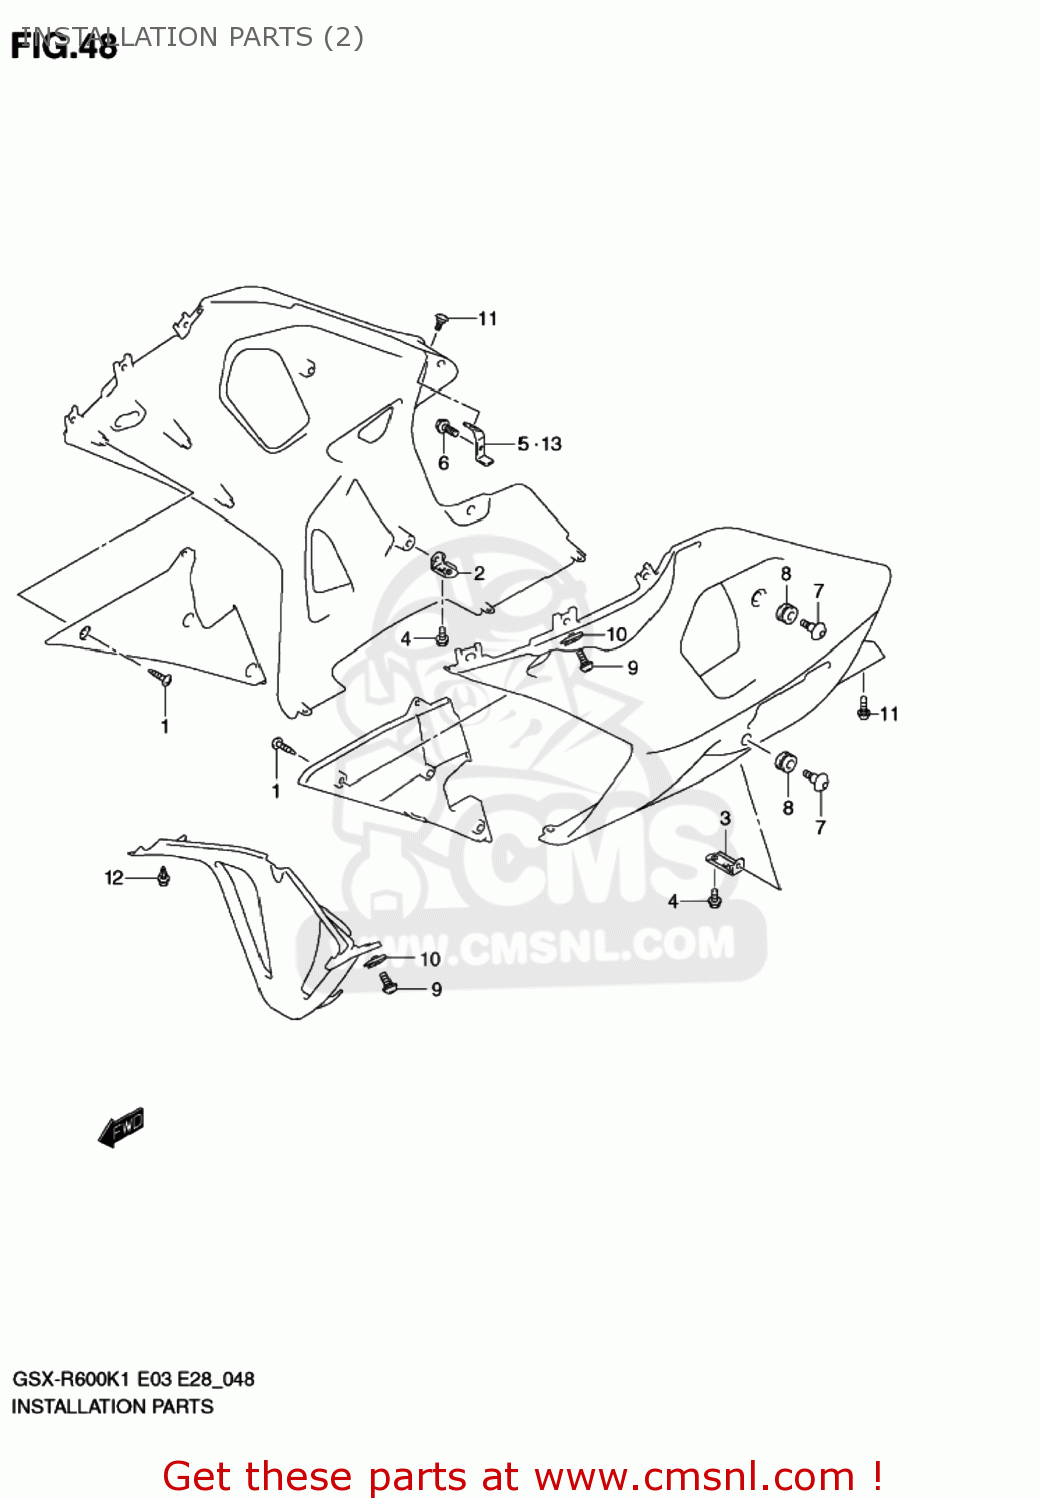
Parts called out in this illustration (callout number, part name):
1	SCREW
2	BRACKET,UNDER COWLING,LOWER
3	BRACKET,UNDER COWLING,LOWER
4	BOLT
5	BRACKET,UNDER COWLING UPR,R
6	BOLT
7	SCREW(6X20)
8	CUSHION
9	SCREW(5X13)
10	NUT,COWL
11	SCREW(5X13)
12	CLIP
13	BRACKET,UNDER COWLING UPR,L
